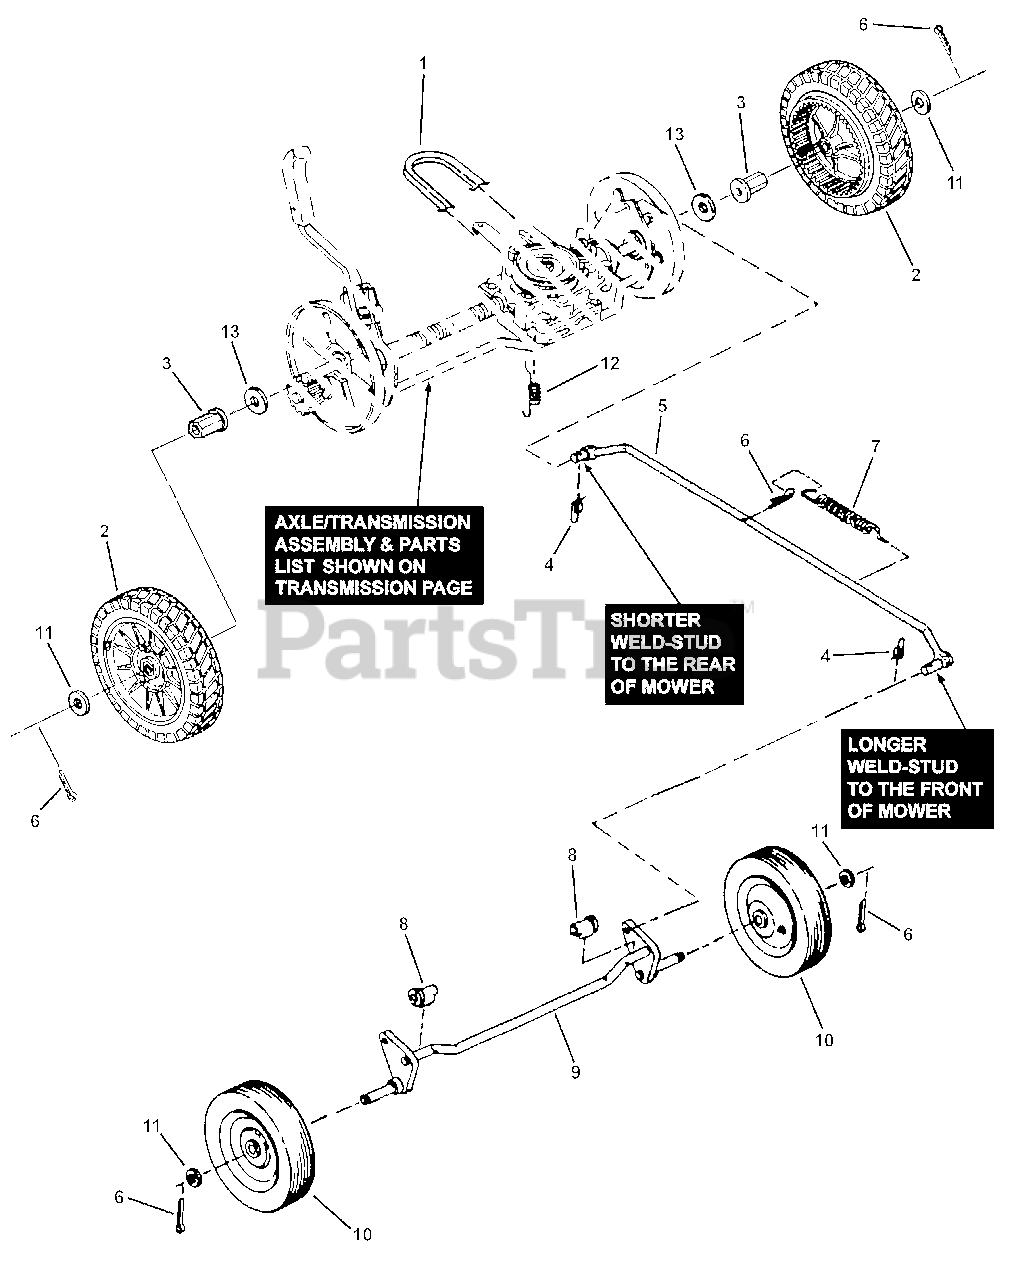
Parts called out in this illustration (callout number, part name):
1	BELT, Traction Drive, Sect. 3L, 33.20" effective length
2	WHEEL, 9.0 x 2.0 (Rear Drive)
3	BUSHING, Wheel (PM)
4	COTTER PIN, 3/8" Self Locking
5	WELDMENT, Tie Bar
6	COTTER PIN, 1/8 x 3/4"
7	SPRING, Tie Bar
8	BUSHING, Front Axle
9	WELDMENT, Front Axle
10	WHEEL, 8.0 x 2.0 (Front)
11	WASHER, .5 x 1.0 x .03 Flat
12	*SPRING, Clutch
13	* WASHER, 17/32" Flat
